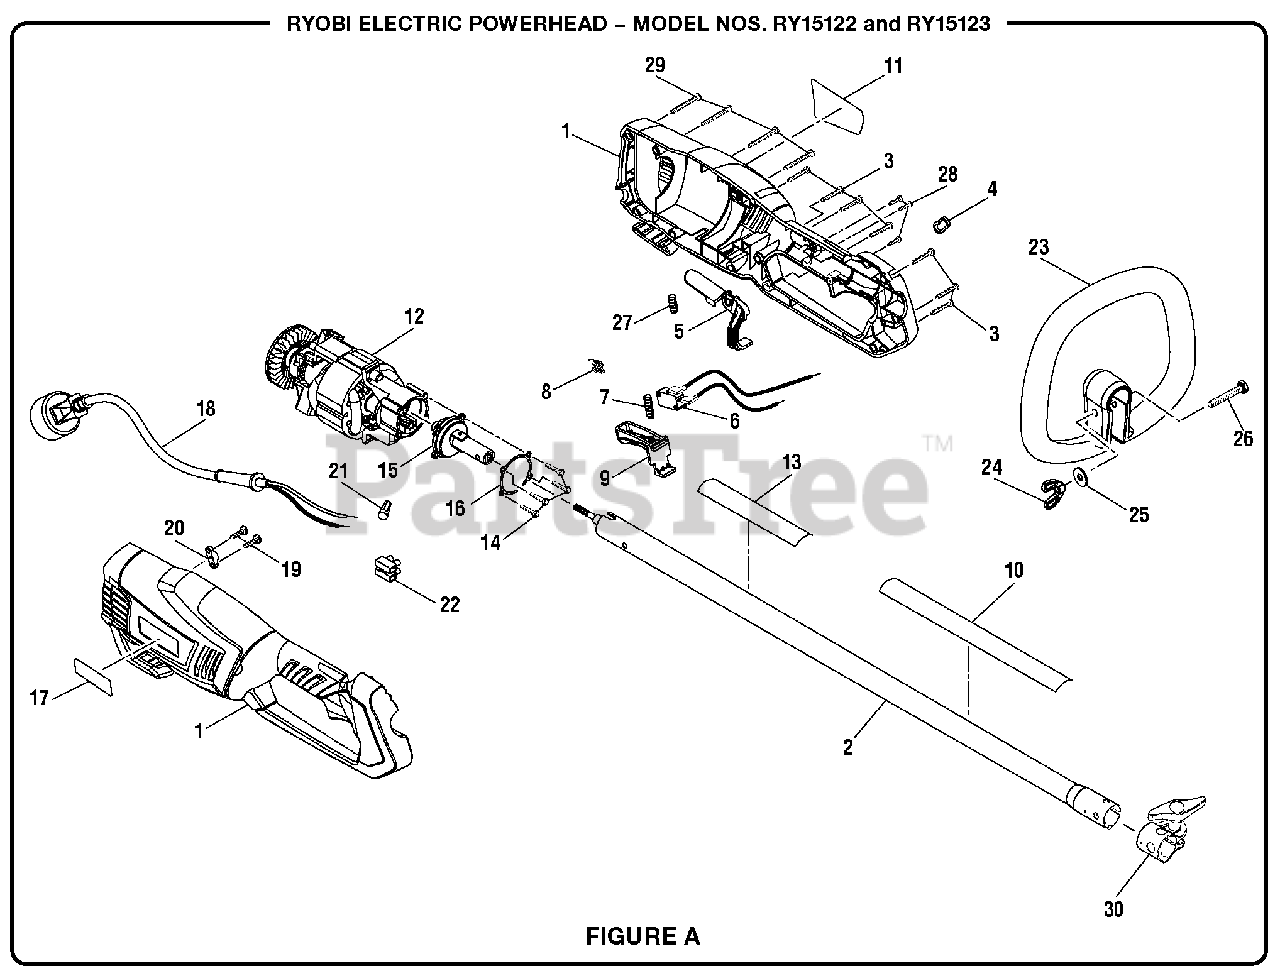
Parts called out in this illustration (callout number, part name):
1	Housing Assembly
2	Boom Assembly
3	Screw (M4 x 14 mm)
4	Strap Hook
5	Lock-Out Lever
6	Switch Assembly w/Leads
7	Compression Spring
8	Torsion Spring
9	Switch Trigger
10	Warning Label (French)
11	Data Label/Warning Label (English and Spanish,
12	Motor Assembly
13	Icon Strip Label
14	Screw (M4 x 10 mm)
15	Gear Assembly
16	Rubber Gasket
18	Power Cord Assembly
19	Screw (M3.5 x 12 mm)
20	Cord Clamp
22	Terminal Block
23	Front Handle Assembly (Inc. Key Nos. 24-26)
24	Wing Nut (1/4-20)
25	Washer (1/4 in.)
26	Bolt (1/4-20 x 40 mm)
27	Compression Spring
28	Screw (M2.9 x 10 mm)
29	Screw (M4 x 18 mm)
30	Boom Clamp Assembly
